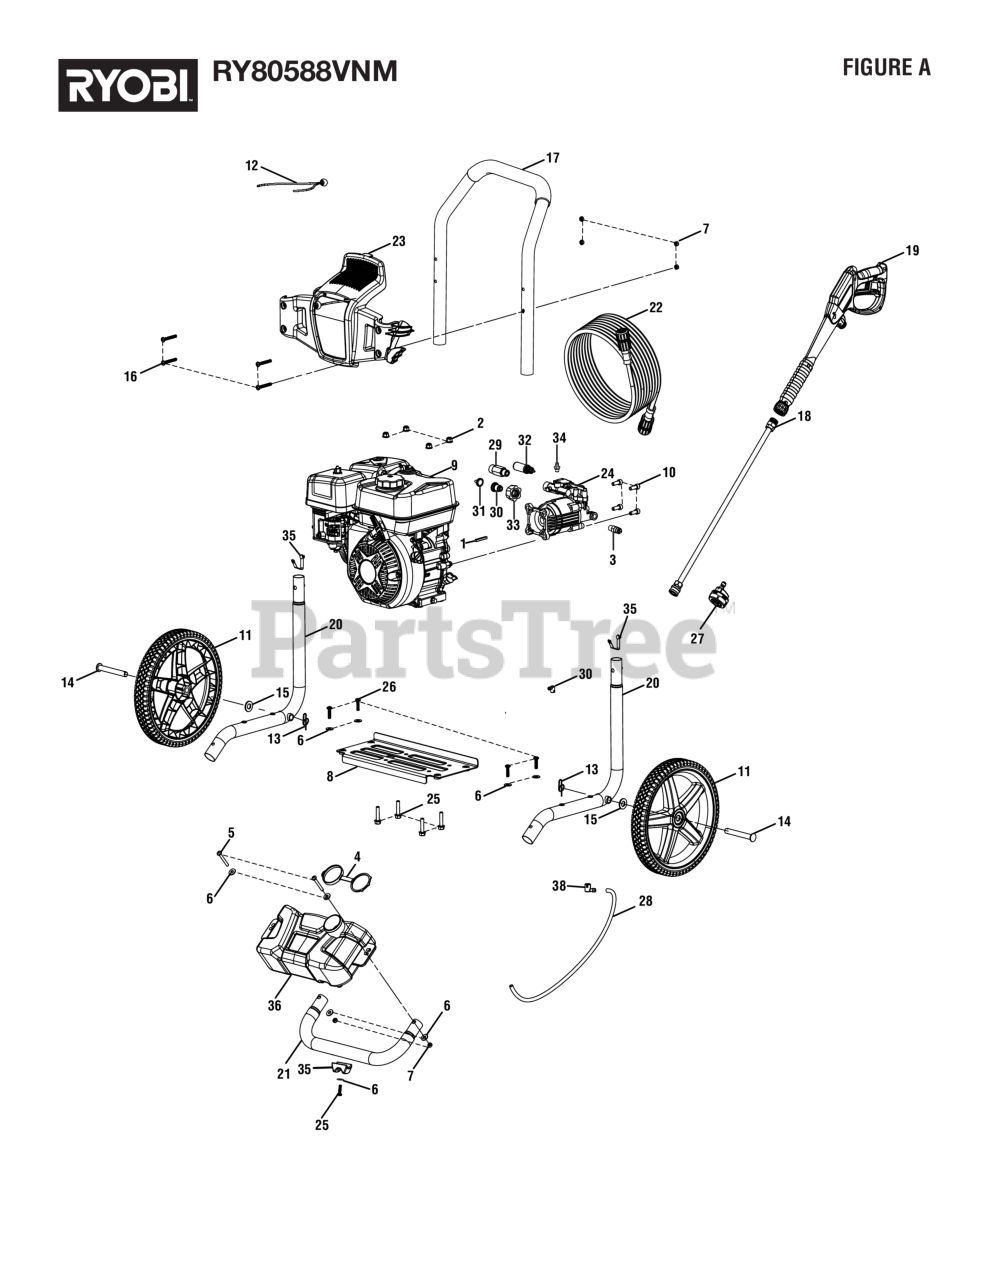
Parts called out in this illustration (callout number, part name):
1	Output Shaft Key (3/16 in. x 40 mm)
2	Lock Nut (M8 x 1.25 mm, Flange)
3	Thermal Release Valve.
4	Detergent Tank Cap
5	Screw (M6 x 1 x 48 mm, T30 Torx Pan Hd.)
6	Washer (1/4 in.)
7	Lock Nut (M6 x 1)
8	Engine Mounting Plate
9	Engine
10	Screw (5/16-24 x 23 mm, Hex Soc. Cap Hd.)
12	Bungee Cord and Bead Assembly
13	Hitch Pin
15	Washer (1/2 in.)
16	Bolt (M6 x 48 mm, Button Hd.)
17	Handle Assembly
18	Extension Wand
19	Trigger Handle Assembly
20	Frame Assembly
21	Front Frame Assembly (Inc. Key No. 33)
22	Hose (35 ft.)
23	Performance Panel
24	Pump (Inc. Key Nos. 57-62)
25	Bolt (M8 x 36 mm, Hex Flange Hd.)
26	Screw (M6 x 1.25in., T30 Torx Pan Hd.)
27	5-in-1 Nozzle
28	Chemical Siphon Tube
29	Outlet Tube
30	Inlet Filter Connector
31	Filter Screen (Pump Inlet)
32	Unloader Valve Assembly
33	Inlet Filter Adapter/Brass Insert
34	Detergent Injector Assembly
35	Rubber Foot
36	Soap Tank
37	Lock Button w/Spring Clip.
38	Soap Hose Inlet Adapter
